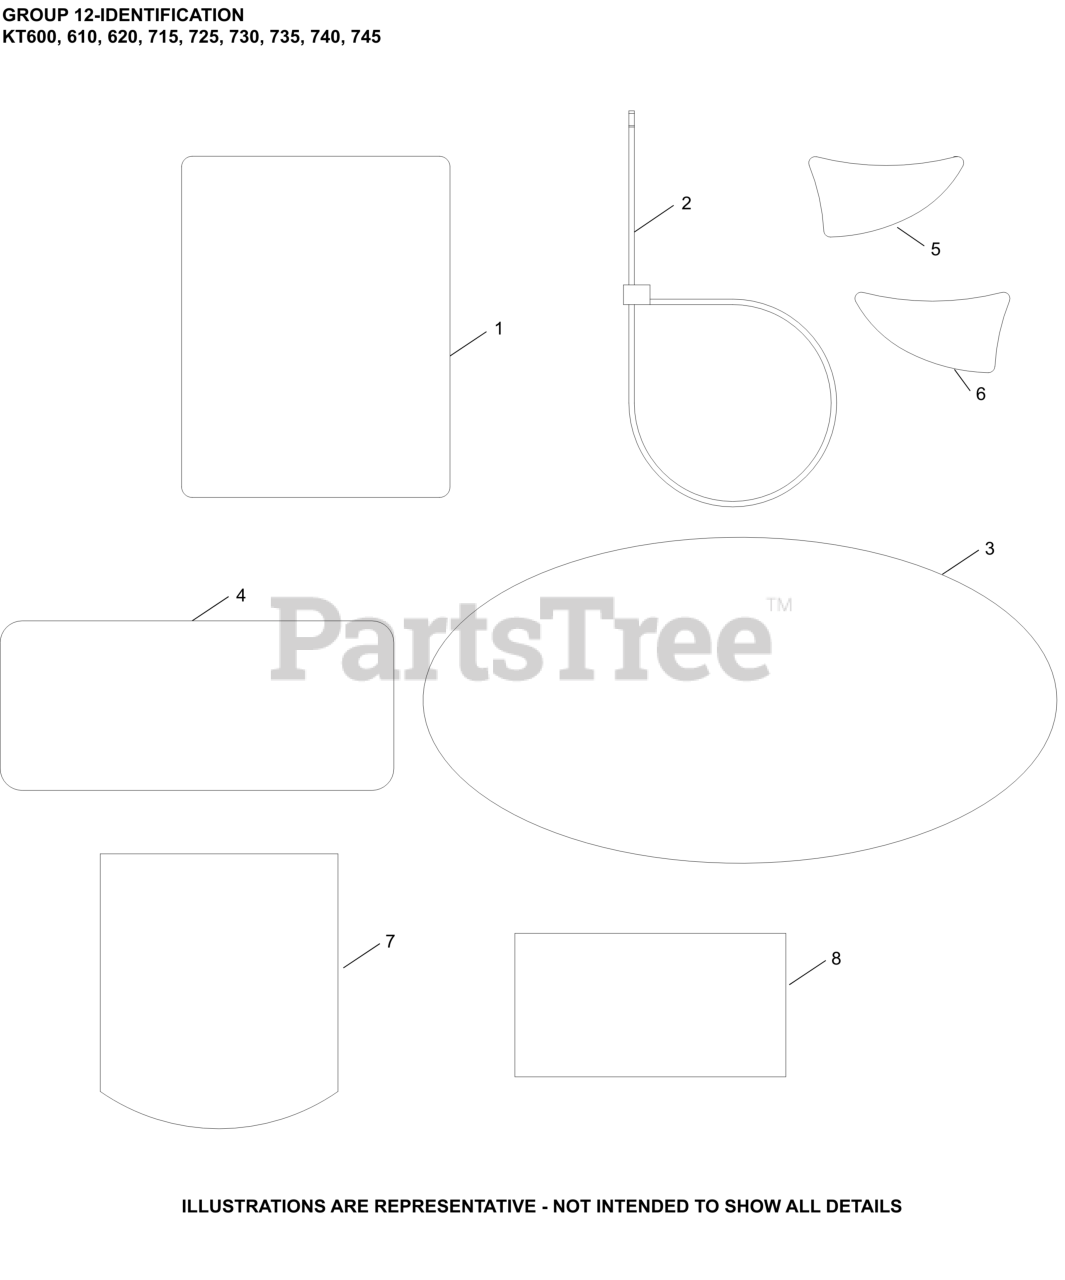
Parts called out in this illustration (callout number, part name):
1	LABEL, CLEAR LAMINATION
3	LABEL, 24HP
8	DECAL, USA
